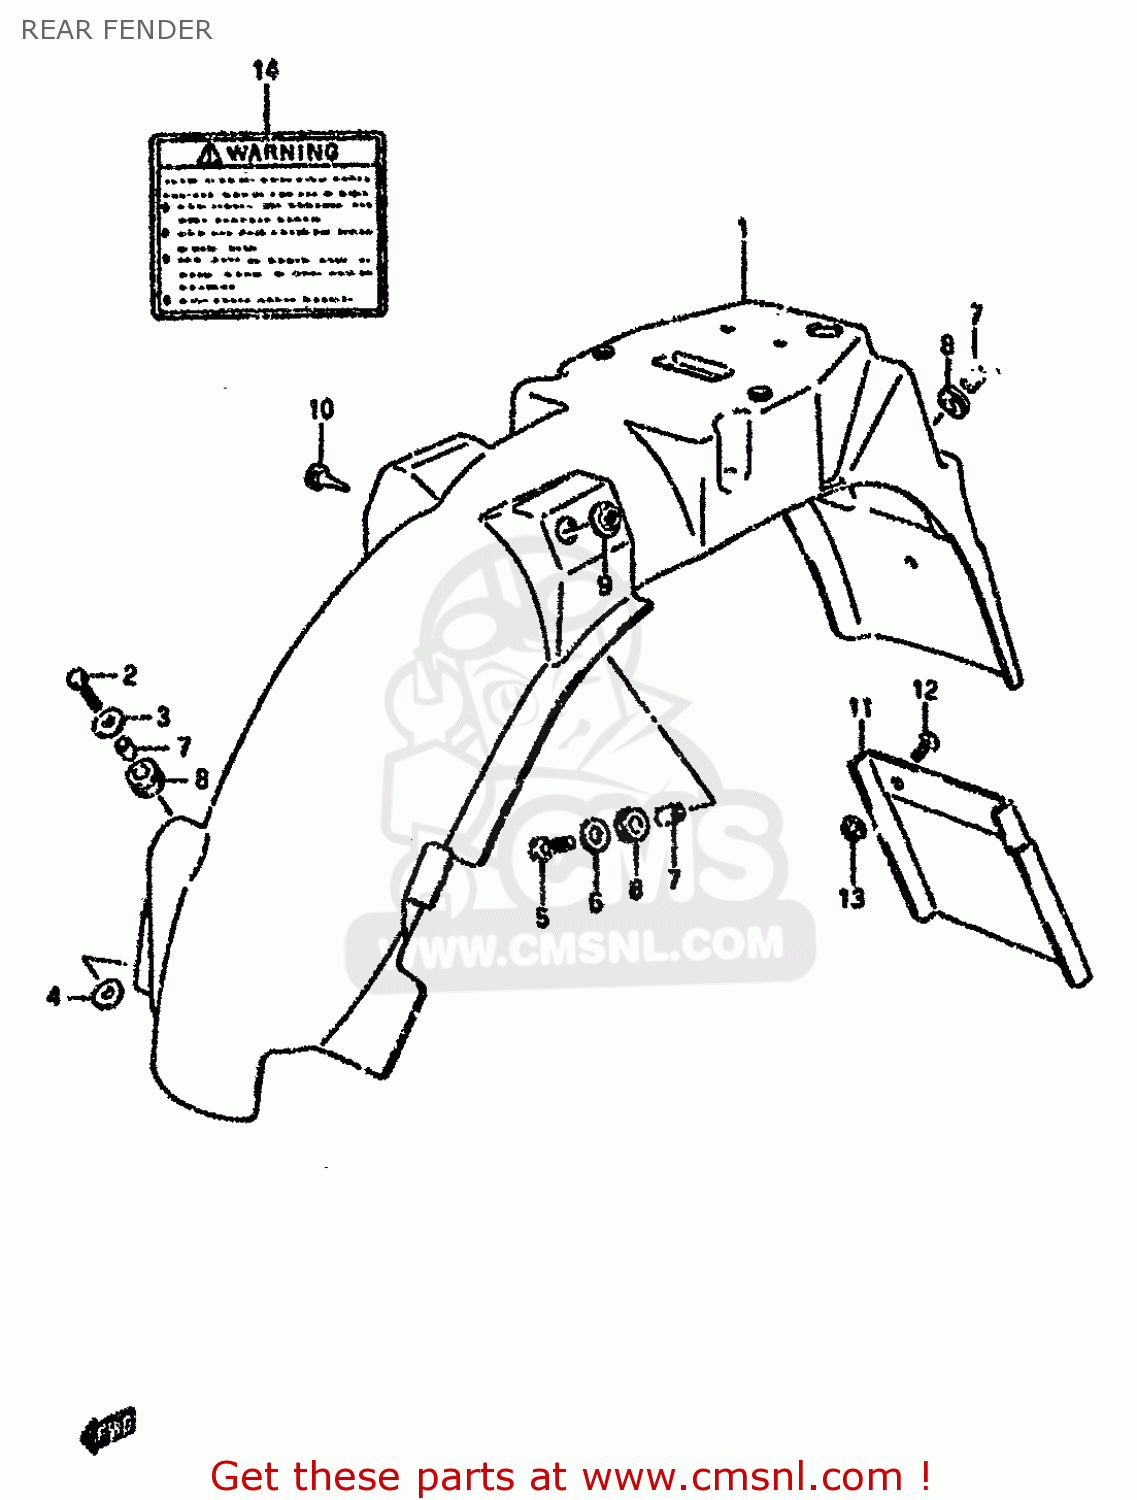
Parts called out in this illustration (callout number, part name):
1	FENDER,REAR
2	BOLT
3	WASHER
4	WASHER(6.5X18X1)
5	BOLT,M6X1X20
6	WASHER
7	SPACER (6.1X9X9)
8	CUSHION
9	NUT 6MM
10	CUSHION
11	EXTENSION,REAR FENDER
12	SCREW
13	NUT
14	LABEL, WARNING SAFETY
15	MANUAL,OWNER'S
